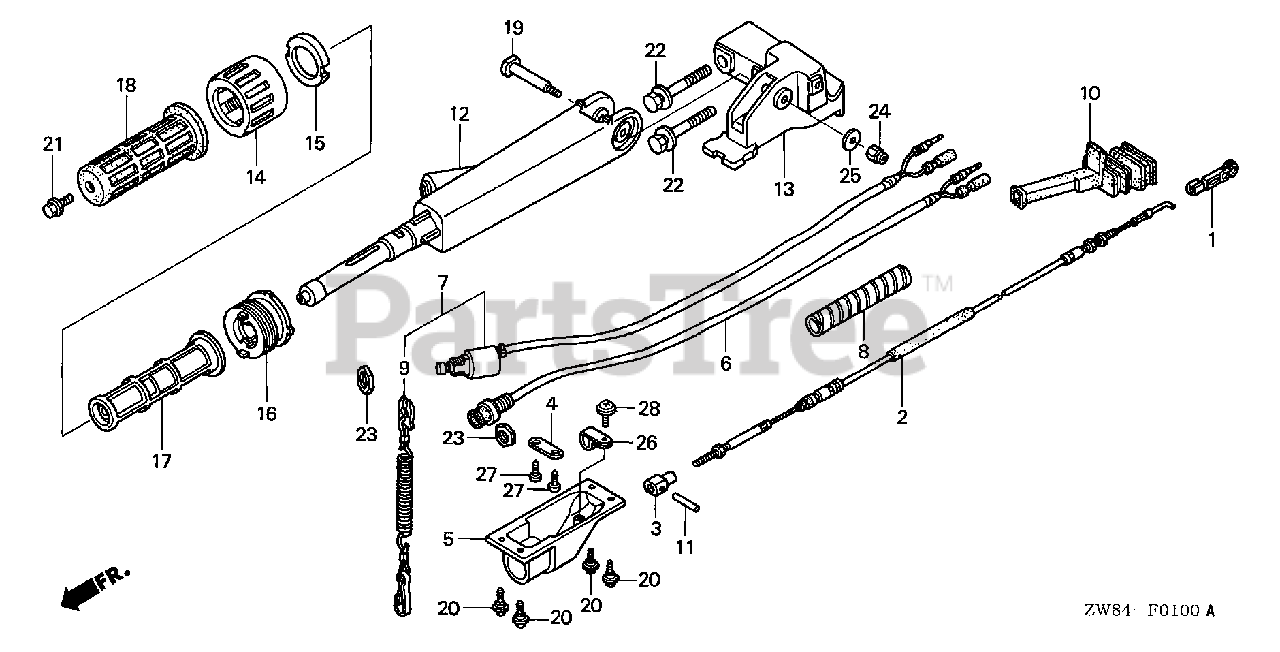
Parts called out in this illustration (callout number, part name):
1	LINKAGE, PIVOT
2	CABLE, THROTTLE
3	PIVOT, THROTTLE CABLE
4	PLATE, SHIFT
5	COVER, STATOR
6	SWITCH ASSY., STARTER
7	SWITCH ASSY., EMERGENCY STOP
8	TUBE, SPIRAL B
9	WIRE, EMERGENCY
10	GROMMET, OIL CASE (A)
11	PIN, THROTTLE CABLE
12	HANDLEBAR *NH246* (LOOSY GRAY)
13	BRACKET, HANDLEBAR *NH246* (LOOSY GRAY)
14	GRIP, THROTTLE FRICTION
15	PAD, THROTTLE FRICTION
16	BLOCK, THROTTLE FRICTION
17	PIPE, GRIP
18	RUBBER, GRIP
19	SCREW, HANDLE PIVOT
20	SCREW, TAPPING (4X10)
21	BOLT, FLANGE (6X12)
22	BOLT-WASHER (10X55)
23	NUT, HEX. (16MM)
24	NUT, SELF-LOCK (8MM)
25	WASHER (8MM)
26	CLIP, WIRE HARNESS
27	SCREW, TAPPING (4X12)
28	SCREW, TAPPING (4X10)
